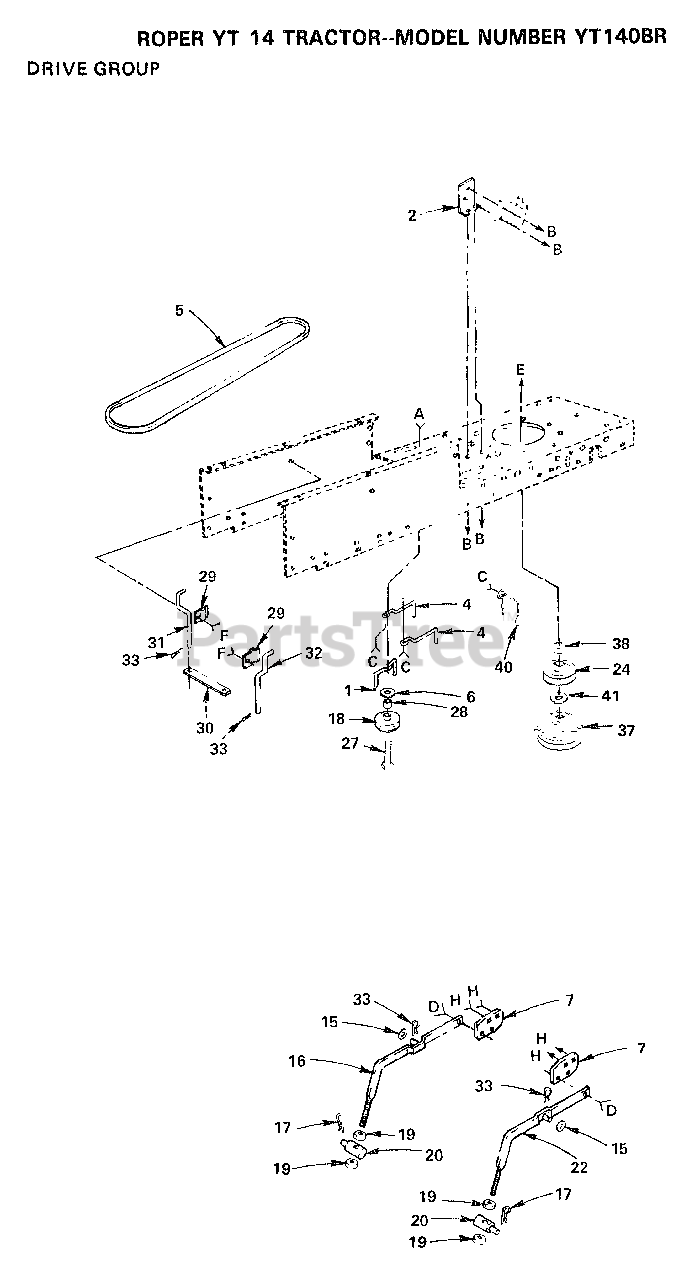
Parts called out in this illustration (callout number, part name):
1	BELT KEEPER LT
2	BRACKET LT
4	"KEEPER,BLT ENG LT"
6	WASHER
7	"BRACKET, SUSPE T"
17	SPRING H
19	NUT
21	NUT LTV
24	PULLEY ENGINE T
27	BOLT
28	SPACER T
29	CLAMP LT
32	KEEPER BELT RH
